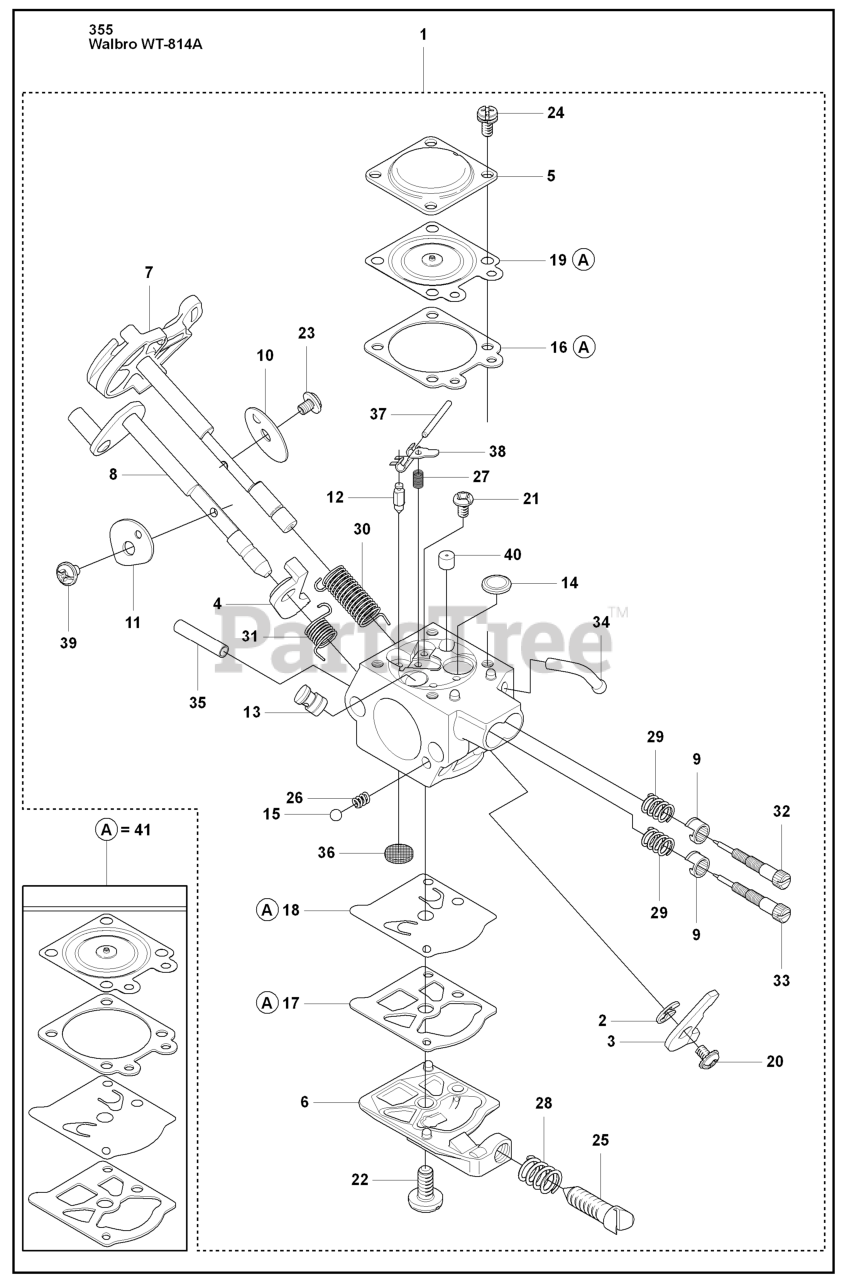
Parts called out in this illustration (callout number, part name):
1	CARBURETOR WT-814A
2	E CLIP
5	DIAPHRAGM COVER
9	LIMITER CAP
12	INLET NEEDLE
14	PLUG
18	DIAPHRAGM, FUEL PUMP
19	METERING DIAPHRAGM
21	SCREW
23	SCREW
24	RP SCREW W/ WASHER
28	SPRING
32	NEEDLE
33	NEEDLE
36	FUEL INLET SCREEN
37	FULCRUM PIN
41	GASKET SET
